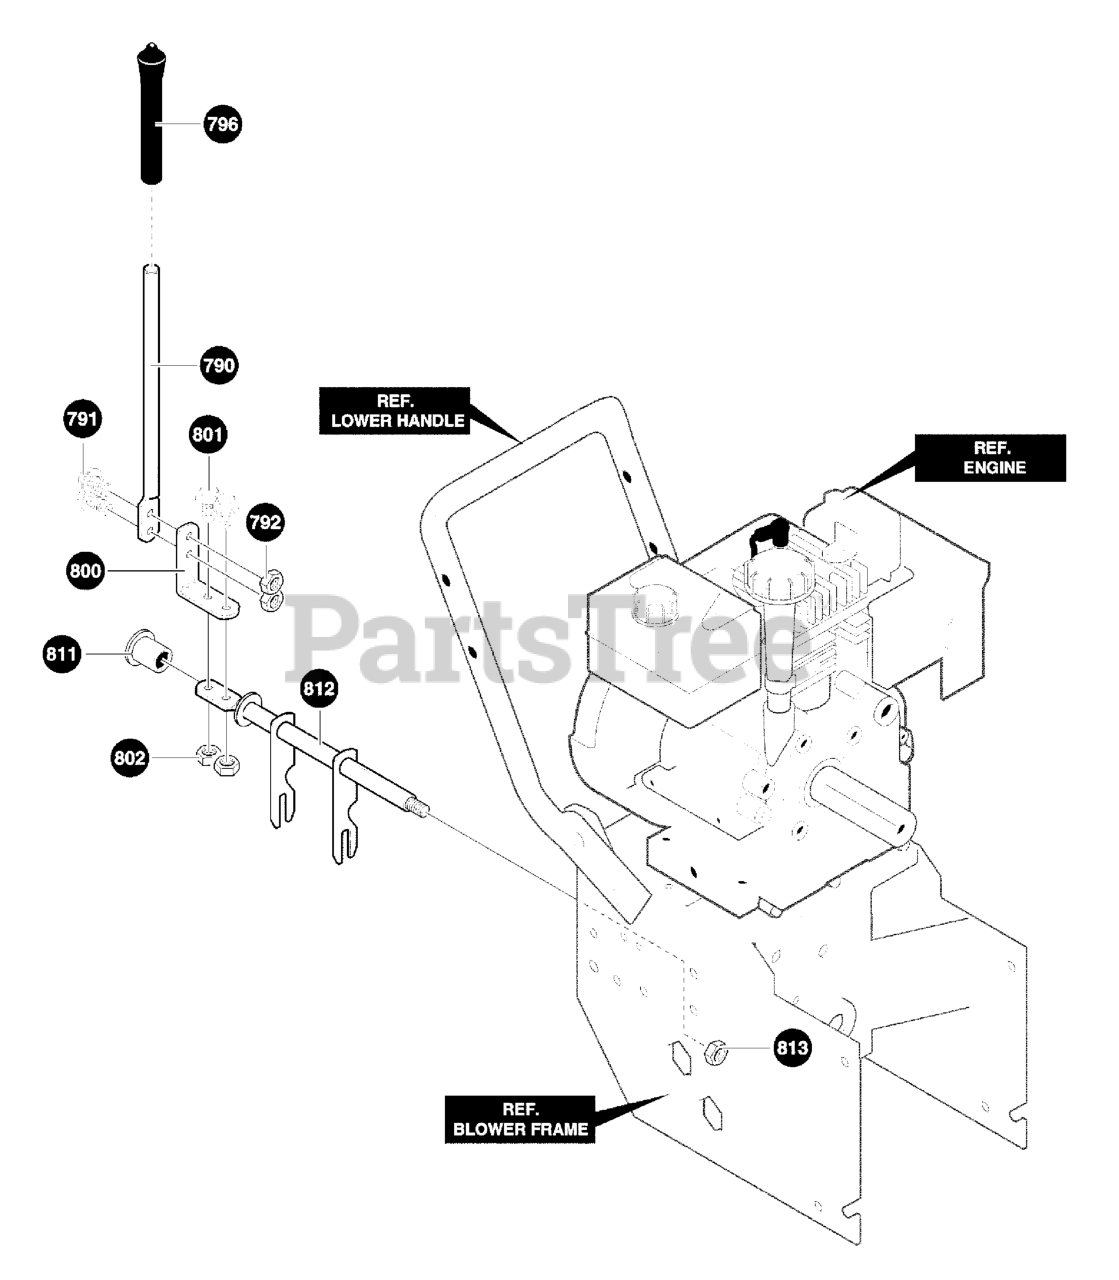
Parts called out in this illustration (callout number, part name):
790	ROD, SHIFT
791	SCREW, 1/4-20X.75
792	NUT, 1/4-20 REGHXCTRLK
796	KNOB, SLIP
800	LEVER, SPRING
801	SCREW, 1/4-20X.75
802	NUT, 1/4-20 REGHXCTRLK
811	BEARING, FLANGE
812	ROD, ASSY YOKE
813	NUT, 3/8-16 HEXCTRLK
